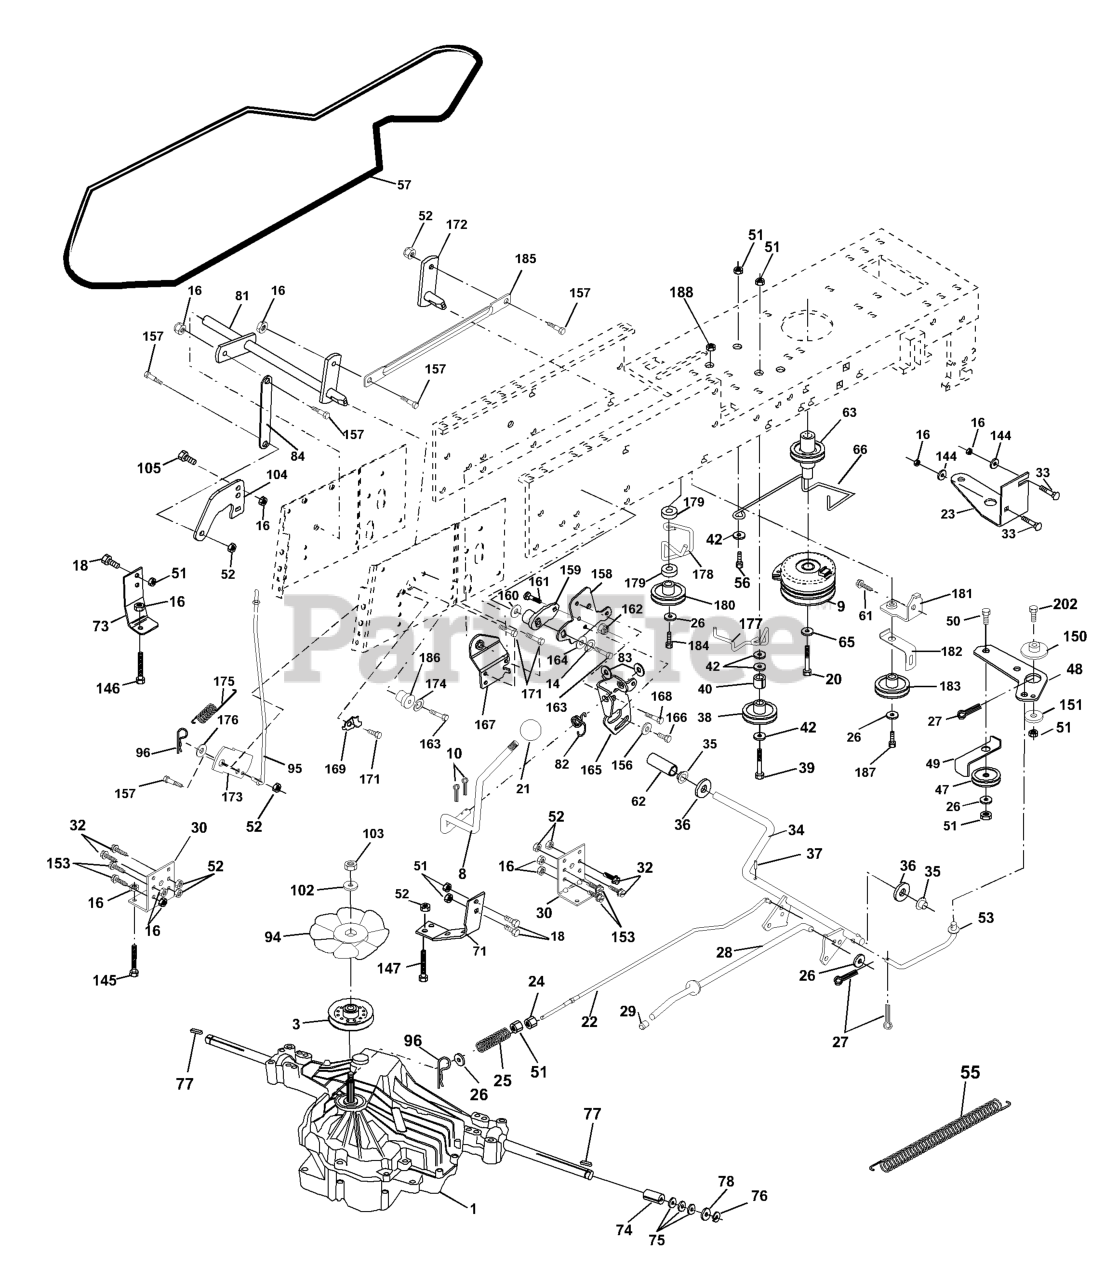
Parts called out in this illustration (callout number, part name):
1	Transaxle Hydro Gear Model 331-0650 (See Breakdown)
3	PULLEY, TRANSAXLE
8	ROD.SHIFT.FENDER.ADJ.LT.CRD
10	PIN COTTER
14	WASHER LOCK
18	BOLT
20	BOLT HEX
21	KNOB.DUCKHEAD.1/2
22	ROD
23	BRACKET.ASM.CLUTCH
24	NUT
25	SPRING
26	WASHER
27	PIN
28	ROD
29	PLUNGER CAP
30	BRACKET TRANSAXLE
33	BOLT
35	BEARING.NYLON
36	WASHER
37	DRIVE PIN
38	PULLEY.FLAT
39	BOLT
42	BOLT
47	IDLER PULLEY
48	BELLCRANK, CLUTCH
49	RETAIN BELT
50	BOLT
51	NUT
52	NUT
53	LINK, CLUTCH LT
55	SPRING, RETURN LT
56	BOLT
57	V-BELT.0650.CRD.TRACTOR
61	SCREW
62	PEDAL COVER T
63	PULLEY, CLUTCH ELECT EVX
65	WASHER
66	KEEPER BELT ENGINE
71	STRAP LH TORQUE
73	STRAP TORQUE RH HYDRO
74	SPACER SPLIT
75	WASHER
77	SQUARE KEY
78	WASHER
82	SPRING,TORSION
83	WASHER
84	LINK TRANSAXLE
94	FAN 7" HYDRO
95	ROD
96	RETAINER SPRING
102	WASHER
103	NUT
104	CONTROL ARM
105	SCREW
144	WASHER
145	BOLT
146	BOLT
147	BOLT
150	BUSHING.BELLCRANK.GRD.DR
151	WASHER
153	BOLT
156	WASHER.SRRTD.5/16
157	BOLT
158	BRACKET
159	HUB
160	WASHER
161	BOLT
162	NUT
163	BOLT
164	WASHER
165	RP BRACKET
167	BRACKET.SUPT.SHIFT.CRD
168	BOLT.SHOULDER.5/16-18X
169	PLATE.FASTENING.CROSS.SHAFT
174	WASHER
175	SPRING.BYPASS.CRD
176	WASHER
180	PULLEY.FLAT.IDLER
181	BRKT.IDLER.GRD.DR.CRD
182	KEEPER BELT
183	PULLEY.V-IDLER
184	SCREW
186	HUB.TAPERED.ROUND.CRD
188	SNAP BUSHING T
190	SCREW
191	BOLT
192	NUT
193	BOLT
194	NUT
